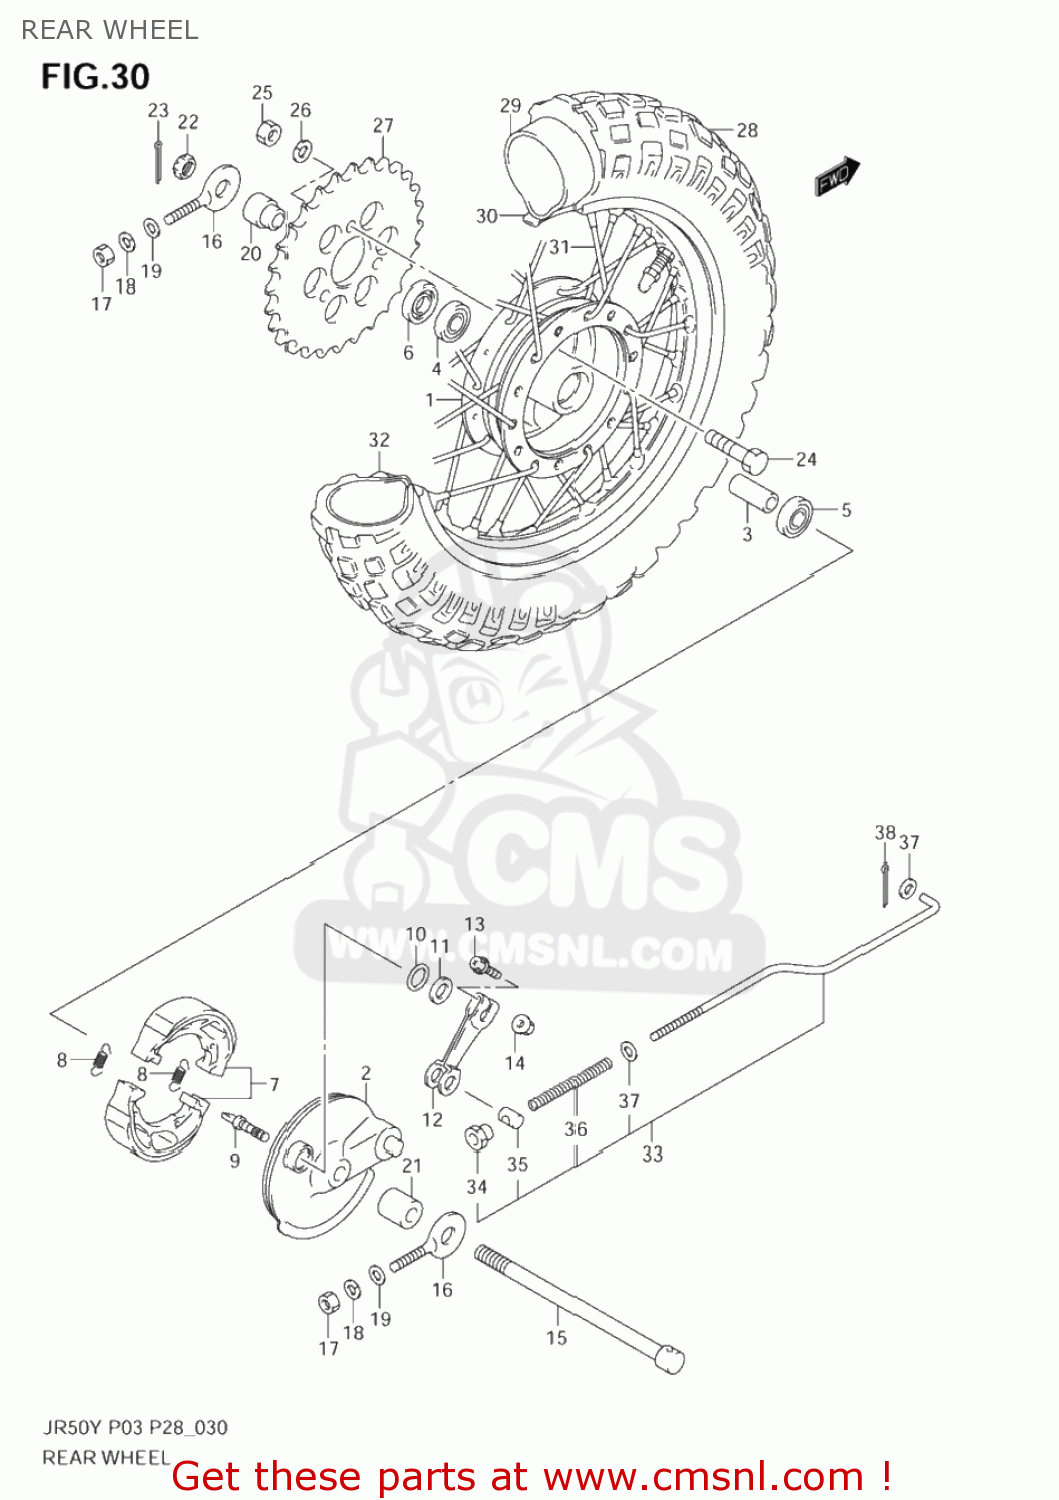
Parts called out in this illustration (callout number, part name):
1	HUB,RR WHEEL
2	PANEL,RR BRAKE ANCHOR
3	SPACER(10.2X16X55)
4	BEARING(10X26X8)
5	BEARING
6	SEAL,OIL(15X27X6)
7	SHOE & SPRING SET (NAS)
8	SPRING(L:35.8)
9	CAM,BRAKE
10	O RING(D:2.4,ID:9.6)
11	WASHER(10.5X18X1)
12	LEVER,RR BRAKE CAM
13	SCREW
14	NUT
15	AXLE,RR
16	ADJUSTER,CHAIN
17	NUT 6MM
18	LOCK WASHER
19	WASHER
20	SPACER,RR AXLE,L
21	SPACER,RR AXLE,R
22	NUT
23	PIN 20X20
24	BOLT(8X36)
25	NUT
26	WASHER,LOCK
27	SPROCKET,RR
28	TIRE
29	TUBE,INNER
30	PROTECTOR,INNER TUBE
31	SPOKE SET,RR
32	RIM,WHEEL
33	ROD ASSY,RR BRAKE
34	NUT
35	PIN,10X19
36	SPRING
37	WASHER
38	PIN
